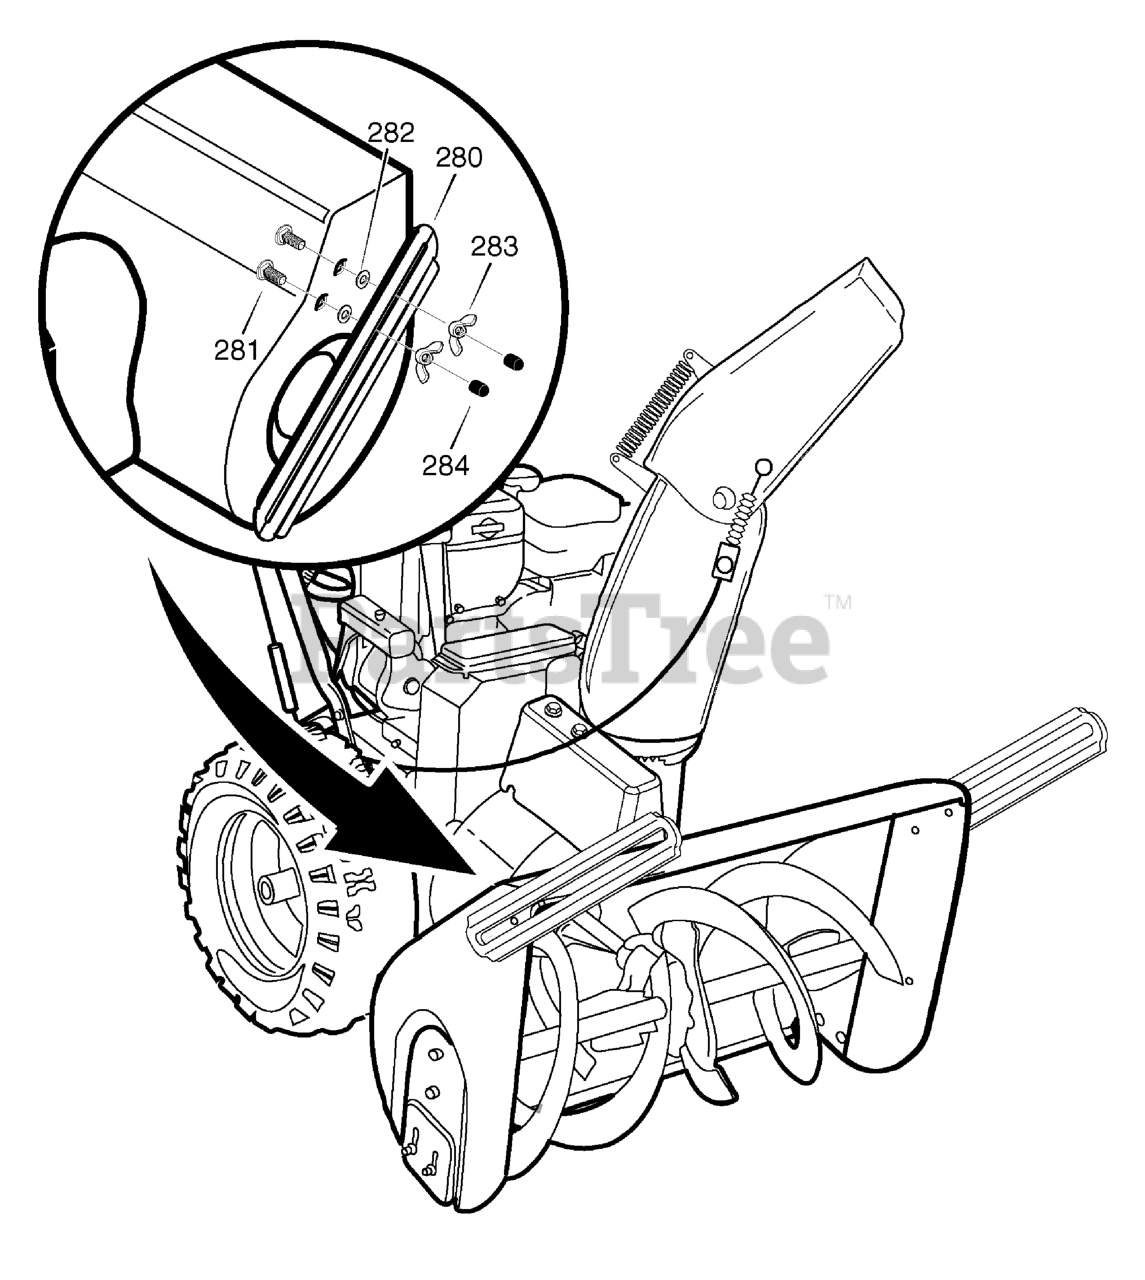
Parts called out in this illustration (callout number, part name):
280	DRIFT CUTTER
281	BOLT
283	WINGNUT
284	STOP, PLASTIC
